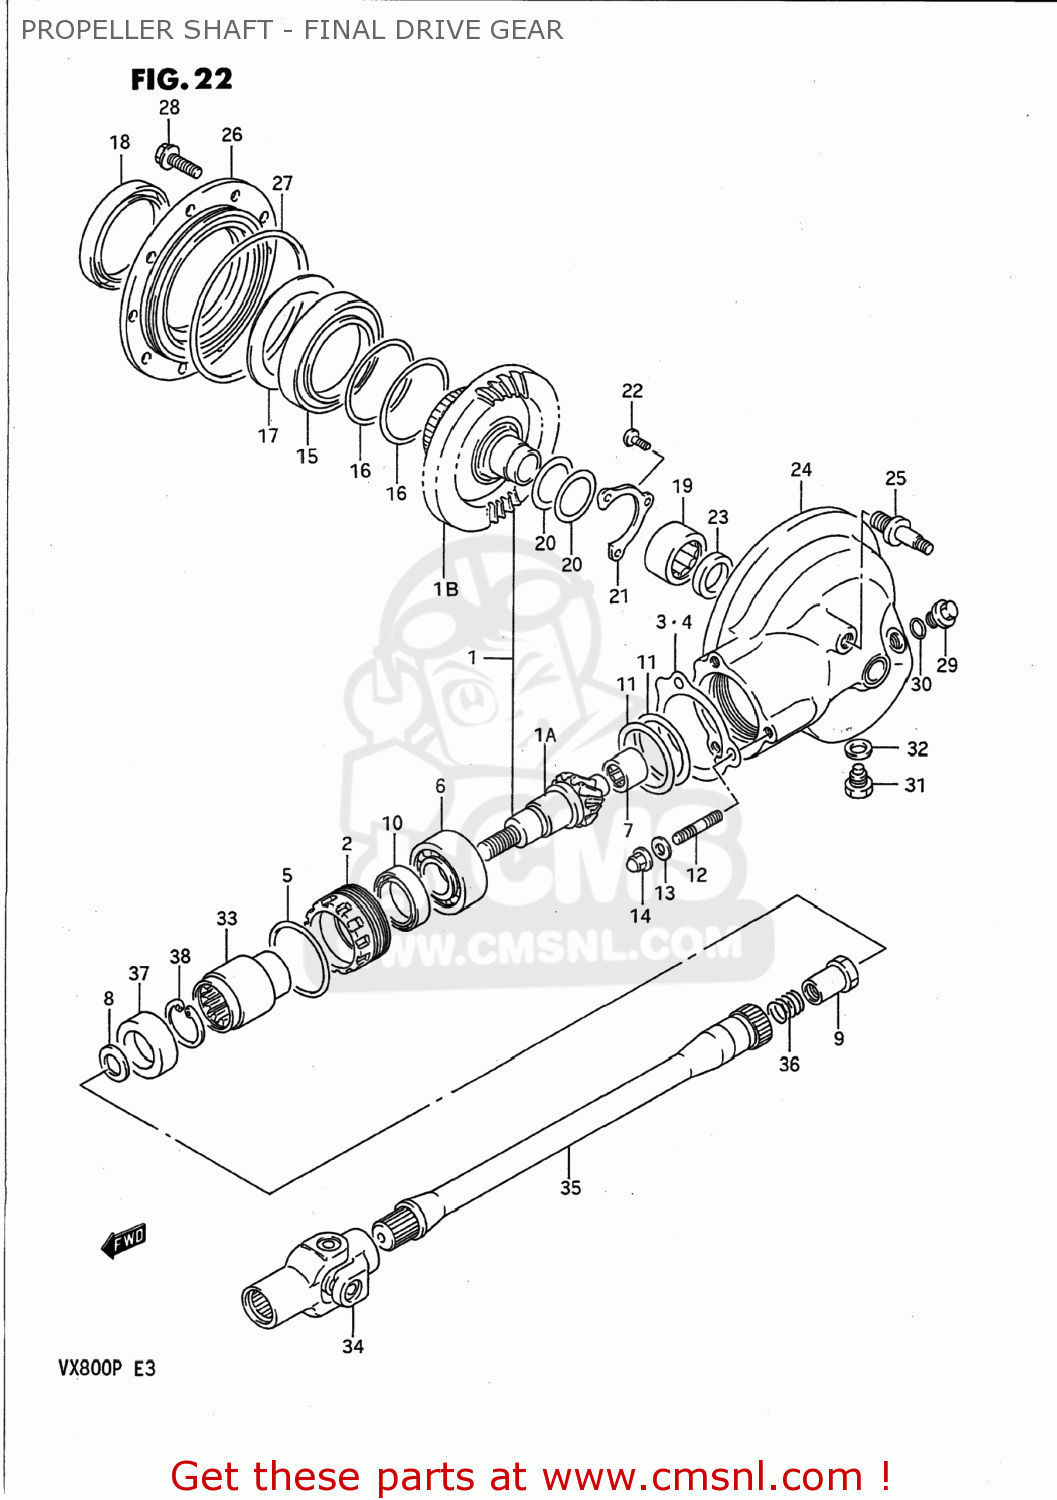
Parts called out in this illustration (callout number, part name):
1	GEAR & CASE SET,FINAL BEVEL
1A	GEAR,FINAL DRIVE BEVEL(NT:11)
1B	GEAR,FINAL DRIVEN BEVEL(NT:34)
2	STOPPER,FINAL DRIVE BEARING
3	PLATE,BEARING STOPPER
4	PLATE,BEARING STOPPER
5	O RING(D:1.9,ID:61.6)
6	BEARING(30X62X23.8)
7	BEARING(17X32X16)
8	WASHER(16X29X4)
9	NUT
10	SEAL,OIL(38X54X6)
11	SHIM,FINAL DRIVE GEAR
12	BOLT,STUD
13	WASHER
14	NUT
15	BEARING(70X110X13)
16	SHIM,DRIVEN GEAR BEARING T0.35
17	PLATE,FINAL DRIVEN BRG OIL
18	SEAL,OIL(70X96X16)
19	BEARING(32X46X17.7)
20	SHIM,FINAL DRIVEN GEAR
21	RETAINER,FINAL DRIVEN GEAR BRG
22	SCREW 6X12
23	SEAL,OIL(30X42X7)
24	CASE,FINAL GEAR
25	BOLT,REAR UNIT STUD
26	CASE,FINAL GEAR BEARING
27	O RING(D:3.5,ID:131.6)
28	BOLT
29	PLUG
30	O RING(D:2.4,ID:17.8)
31	PLUG
32	GASKET(14X19.2X2) (NAS)
33	COUPLING,FINAL DRIVE GEAR
34	YOKE COMP,UNIVERSAL JOINT
35	SHAFT,PROPELLER
36	SPRING
37	SEAL,OIL(28.4X48X15)
38	CIRCLIP
